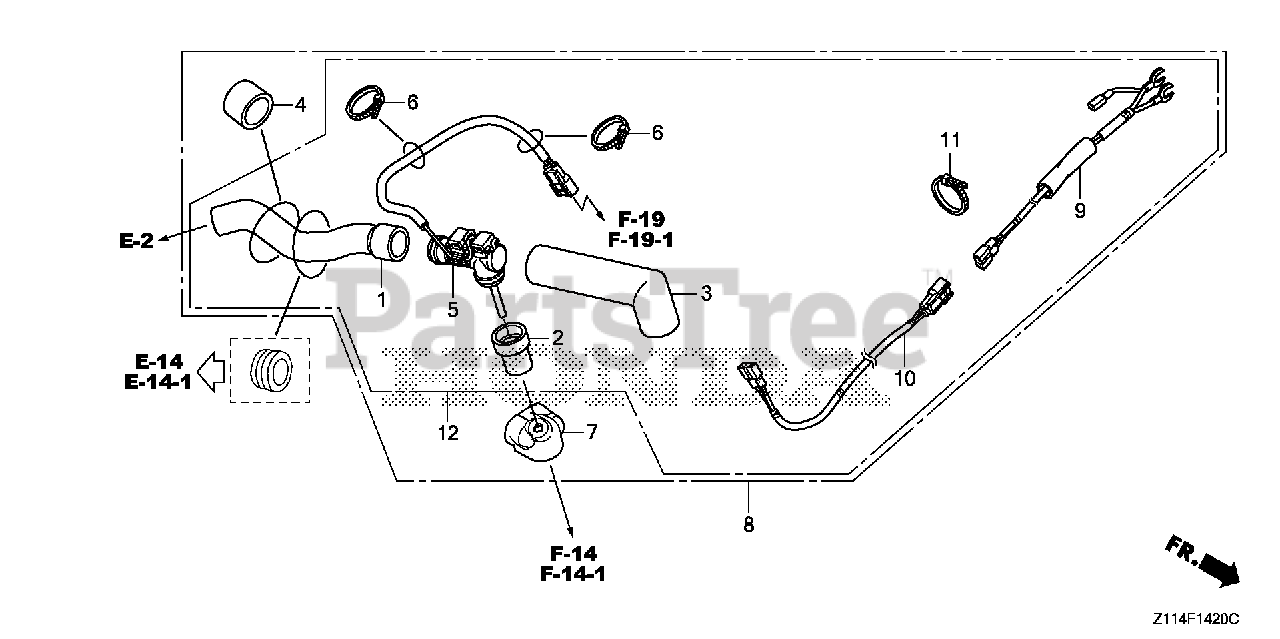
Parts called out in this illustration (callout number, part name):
1	TUBE A, BREATHER
2	TUBE B, BREATHER
3	INSULATOR, BREATHER TUBE
5	HEATER ASSY., BREATHER
6	BAND A, HARNESS (NATURAL)
9	SUB-WIRE ASSY.
10	WIRE ASSY., EXTENSION
11	BAND A, HARNESS (NATURAL)
12	HEATER KIT, BREATHER
